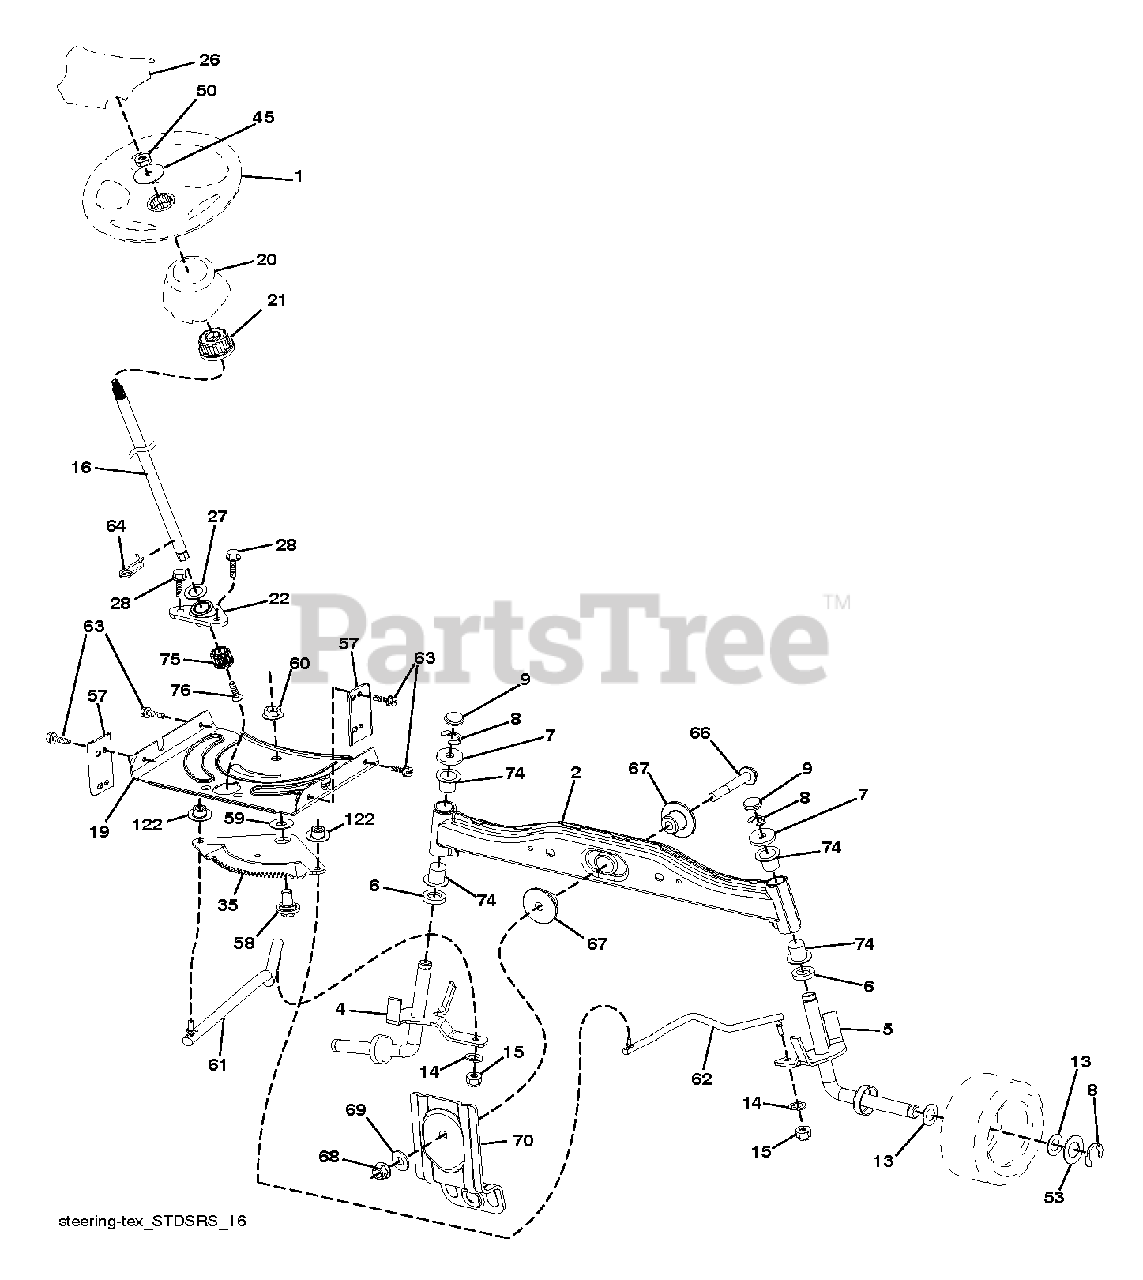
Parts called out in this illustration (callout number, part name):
1	WHEEL.STEERING.MLT.BR.YEL/OVRM
2	AXLE HALF ASM-WELDED
4	SPINDLE.WELDED.LH.15"TEX
5	SPINDLE.WELDED.RH.15"T
8	RING CLIP
9	CAP.SPINDLE.BLACK
14	WASHER, LOCK 3/8
15	NUT CROWNLOCK 3/8-24
19	PLATE.STEER.DDL.NLT/NG
20	BOOT.STRNG.PREDATOR.YT/GT.428
26	CAP.WHL.STRNG.MULTI.BRND.YEL
27	WASHER LT
28	SCREW, 3/8-16X3/4
35	GEAR.SECTOR.PLATE.DDL.
45	WASHER.3/8ID.2-3/8OD.12GA.PLTD
50	NUT LOCK FLG 3/8-16 UNC
53	WASHER.HARDENED
57	BRACKET.UPSTOP.TEX
58	BOLT.SHOULDER.SECTOR.P
59	WASHER.THURST.SECTOR.S
60	NUT FLANGE LOCK 5/8-11
61	DRAGLINK.LH.BALLSTUD.D
62	DRAGLINK.RH.BALLSTUD.D
63	SCREW
64	RETAINER.CLIP.SPRING.S
66	BOLT HEX FGHD 7/16-14 X 3 SERR
67	BUSHING.PM.FRONT AXLE
68	NUT.LOCK.FLANGE.7/16
69	WASHER.1.5X.505X.118
70	Deck Suspension Bracket, Front RR
74	Steering Column Bearing
76	Screw Head Socket Lrvb
122	CAP.GEAR.SECTOR.TEX
